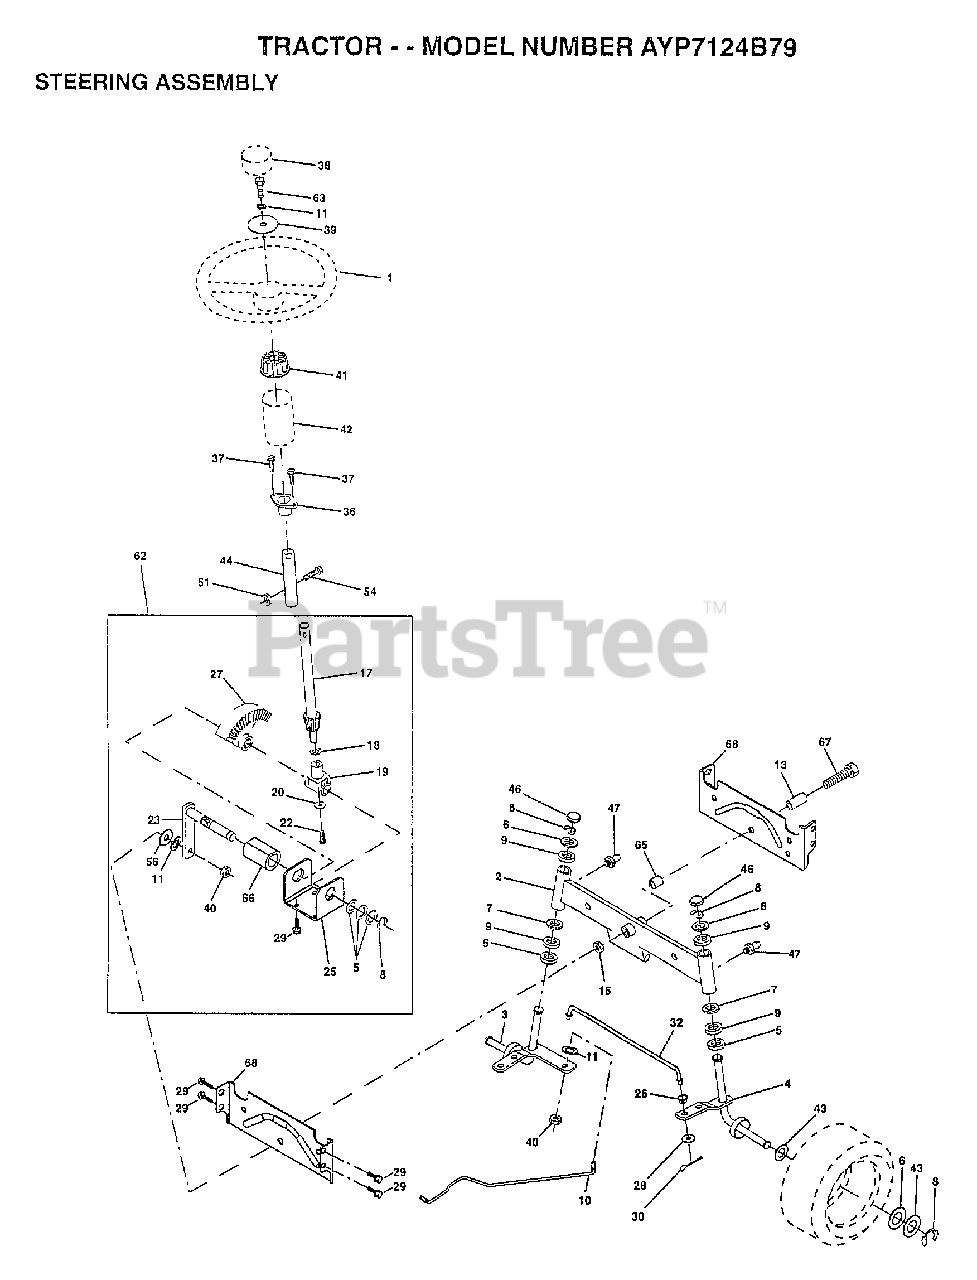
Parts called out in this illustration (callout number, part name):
1	CONTROL THROTTLE
2	SCREW LT
4	MUFFLER
13	GASKET ENG 1 313 LD TIN PLATED
14	PIPE NIPPLE
15	ELBOW
16	LOCKWASHER
23	SHIELD-HEAT
31	TANK.FUEL.LT.
32	CAP ASM FUEL
33	HOSE CLAMP
35	SCREW
37	LINE FUEL
44	SCREW HEX CRT
46	WASHER
62	LOCKWASHER
72	SCREW
78	SCREW
81	NUT
